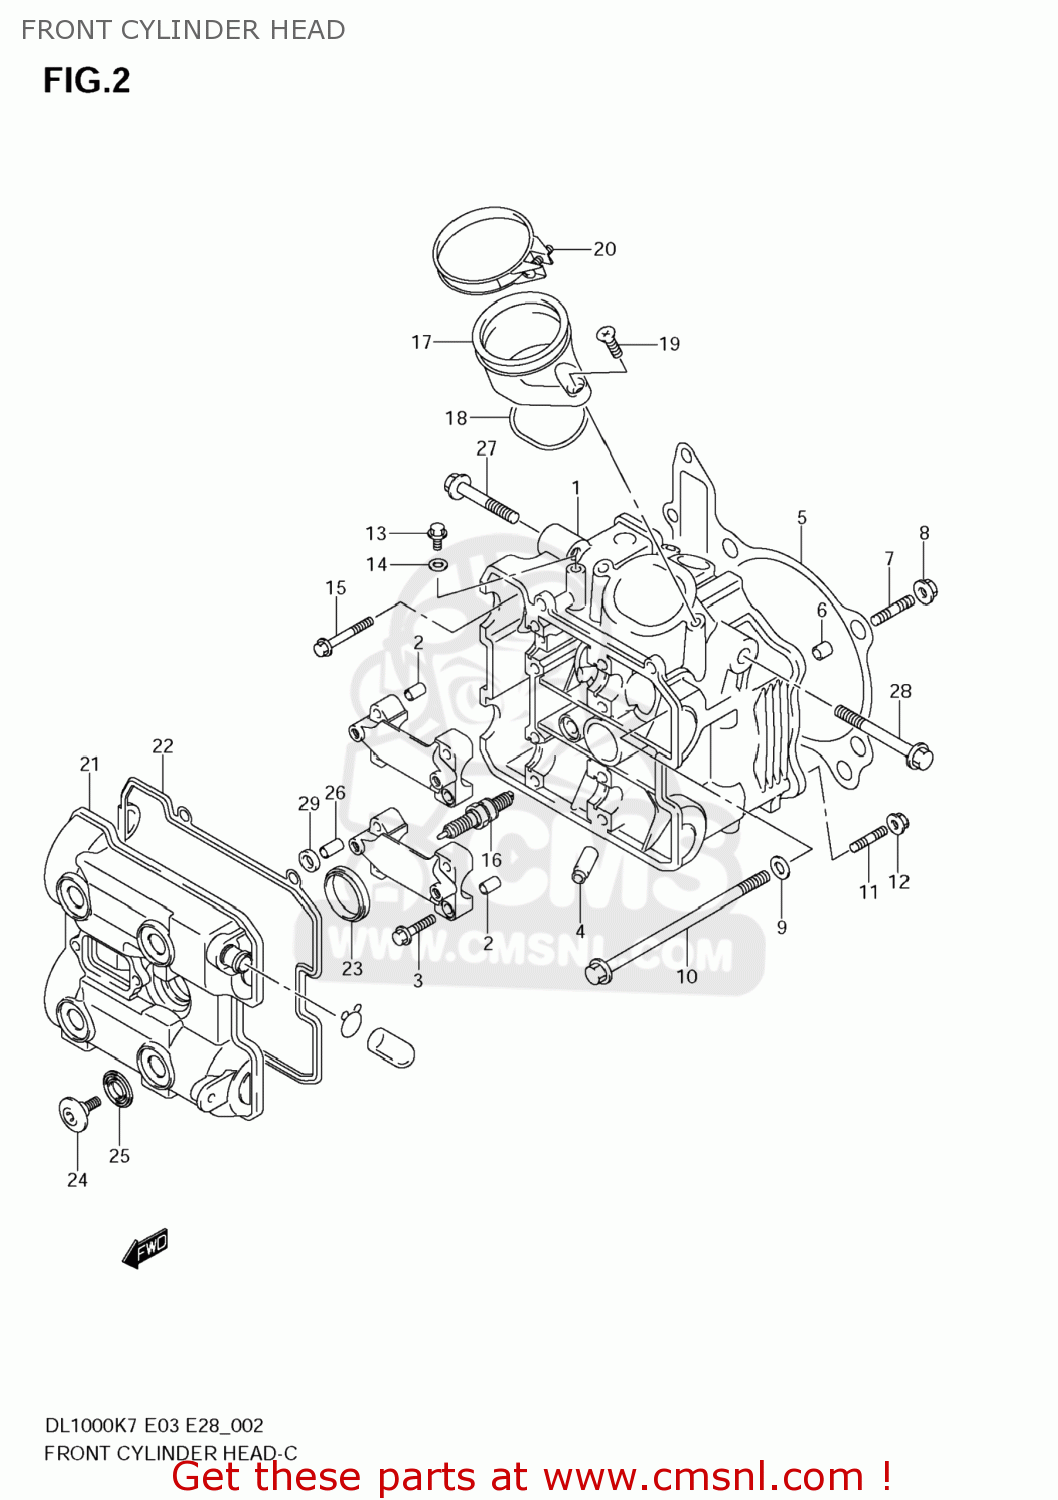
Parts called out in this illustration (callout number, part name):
1	HEAD ASSY,CYLINDER FR
2	PIN(6.2X8X11)
3	BOLT(6X39)
4	GUIDE,VALVE
5	GASKET,CYLINDER HEAD (NAS)
6	PIN
7	BOLT,STUD
8	NUT
9	WASHER(10.5X19X2)
10	BOLT(10X175)
11	BOLT,STUD
12	NUT
13	BOLT
14	GASKET(5.8X13X1.2) (NAS)
15	BOLT(6X70)
16	PLUG,SPARK(CR8EK)
17	PIPE ASSY,INTAKE FR
18	O RING(D:2.4,ID:55.6)
19	SCREW
20	CLAMP
21	COVER,CYLINDER HEAD FR
22	GASKET,CYL HEAD COVER NO.1 (NAS)
23	GASKET,CYL HEAD COVER NO.2
24	BOLT(7X17.5)
25	WASHER,CYL HEAD COVER
26	PIN(6.2X8X16)
27	BOLT(10X65)
28	BOLT(10X85)
29	GASKET,2ND AIR PASSAGE (NAS)
